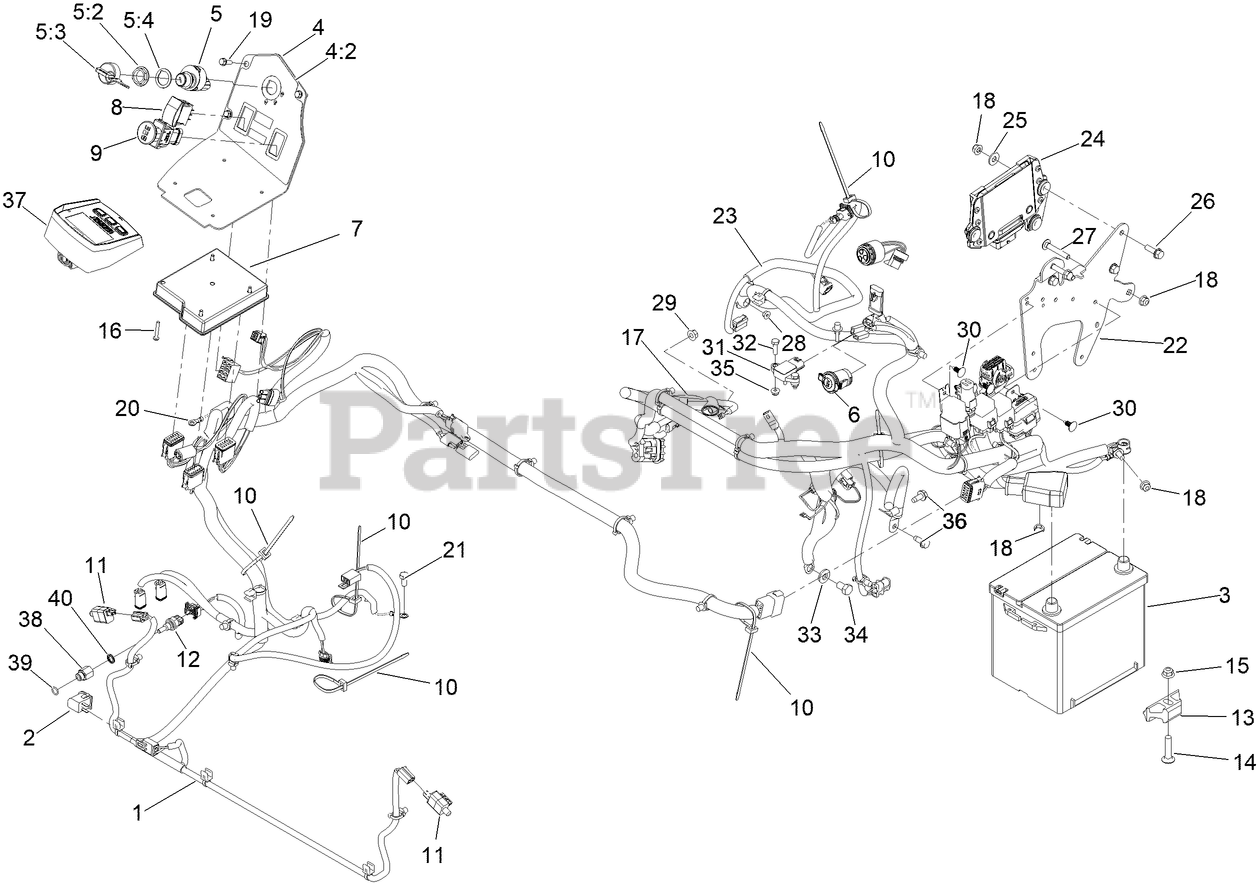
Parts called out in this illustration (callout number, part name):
1	HARNESS-WIRE
2	SWITCH-BAIL
3	BATTERY-DRY
4	CONSOLE ASM
4:2	DECAL-CONTROL PANEL
5	IGNITION SWITCH ASM
5:2	NUT-MOUNTING
5:3	IGNITION KEY SET
5:4	WASHER-BACKUP
6	PORT-POWER, 12V
7	MODULE-MCU
8	SWITCH
9	SWITCH-PTO, SEALED
10	TIE-CABLE
11	SWITCH
12	SENSOR-TEMPERATURE
13	RETAINER-BATTERY
14	SCREW-CARR
15	NUT-HF, NI
16	SCREW-PPH
17	CABLE-BATTERY
18	NUT-HF, NI
19	SCREW-HWH
20	HARNESS-WIRE, JUMPER
21	BOLT
22	BRACKET-MOUNT, ECU
23	HARNESS-WIRE, YANMAR
24	ECU ASM-SERVICE
25	WASHER-FLAT
26	SCREW-HHF
27	BOLT-CARR
28	NUT-HF
29	NUT-HF
30	PLUG-PLASTIC
31	SENSOR-ATM
32	SCREW-HH
33	WASHER-BELLEVILLE
34	SCREW-HH
35	NUT-HF
36	SCREW-HWHTF
37	MODULE-HORIZON
38	FITTING-STR, 6MORB-M12, STL, CZ
39	O-RING
40	WASHER-SEAL, M12
